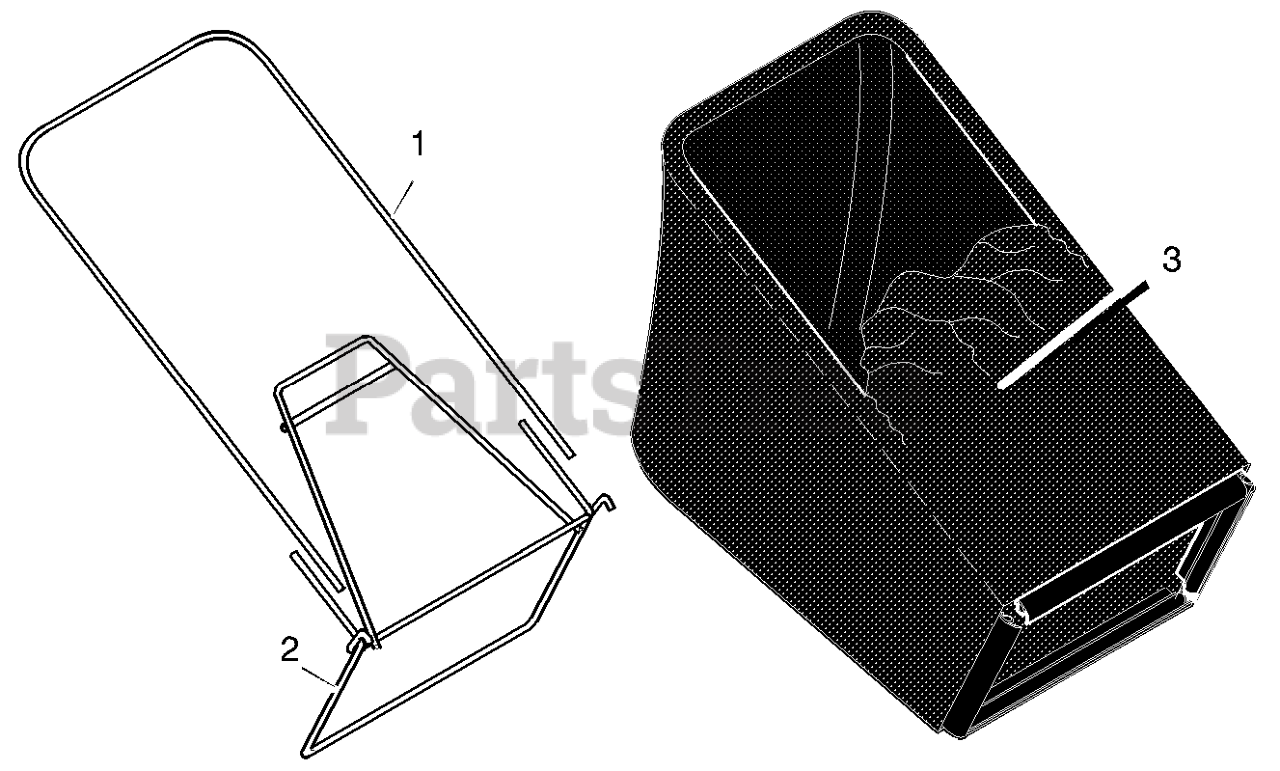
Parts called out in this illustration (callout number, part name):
1	Frame, Top
2	Frame Assembly
3	Bag, Cloth
